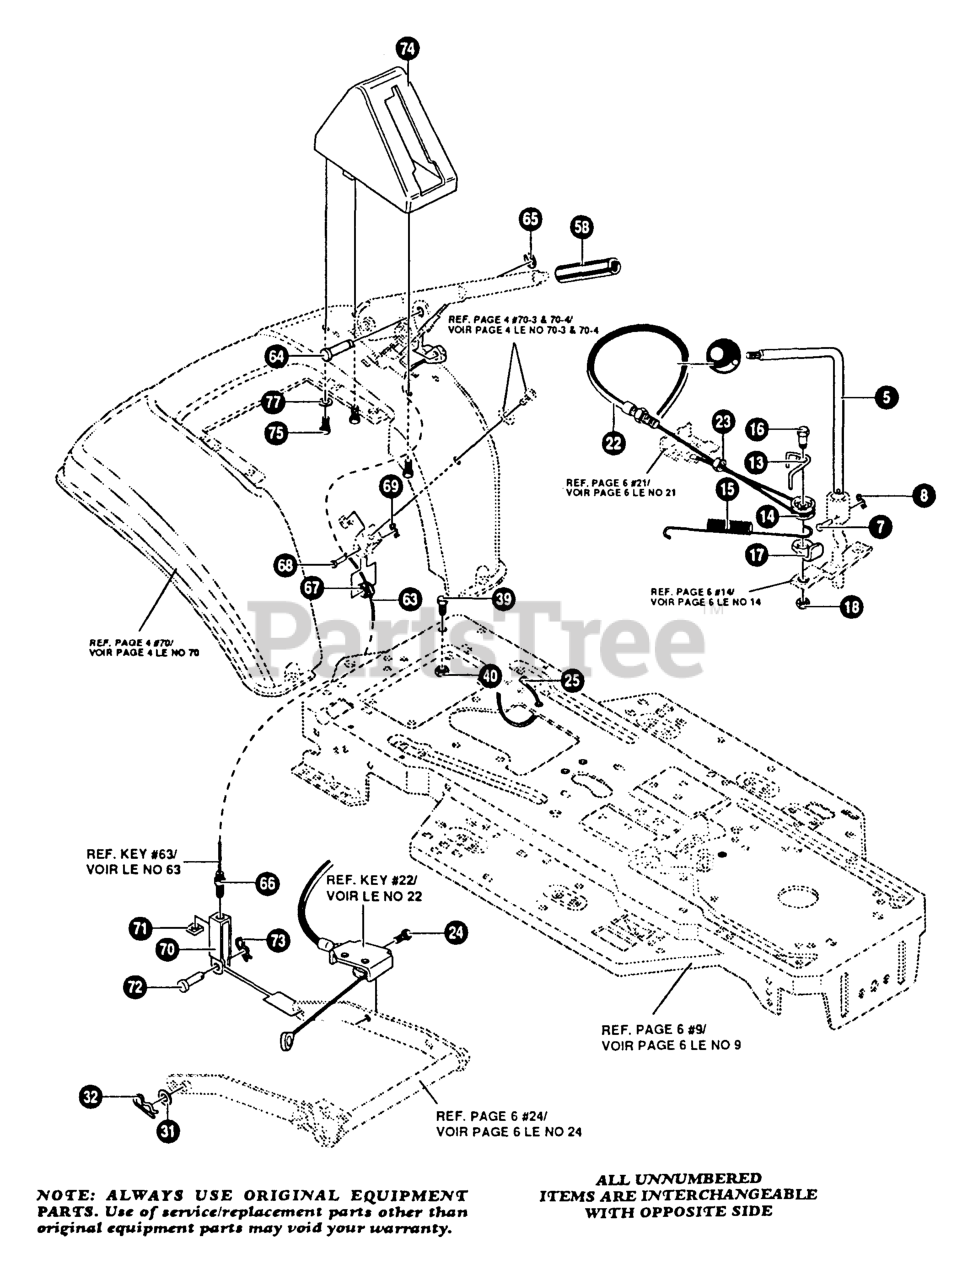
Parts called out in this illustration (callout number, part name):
5	LEVER, PTO UPPER
7	PIN, CLEVIS
8	PIN, HAIR
13	SPRING, CABLE KEEPER
17	BRKT, CABLE
22	ASST, CABLE ENG
24	SCREW
25	TIE, CABLE
32	PIN, HAIR
39	SCREW
63	ASSY, CABLE LIFT
64	PIN, CLEVIS
65	RING RET E
68	PIN, CLEVIS
70	CLEVIS LIFT CABLE
72	PIN, CLEVIS
74	LIFT COVER
77	WASHER
